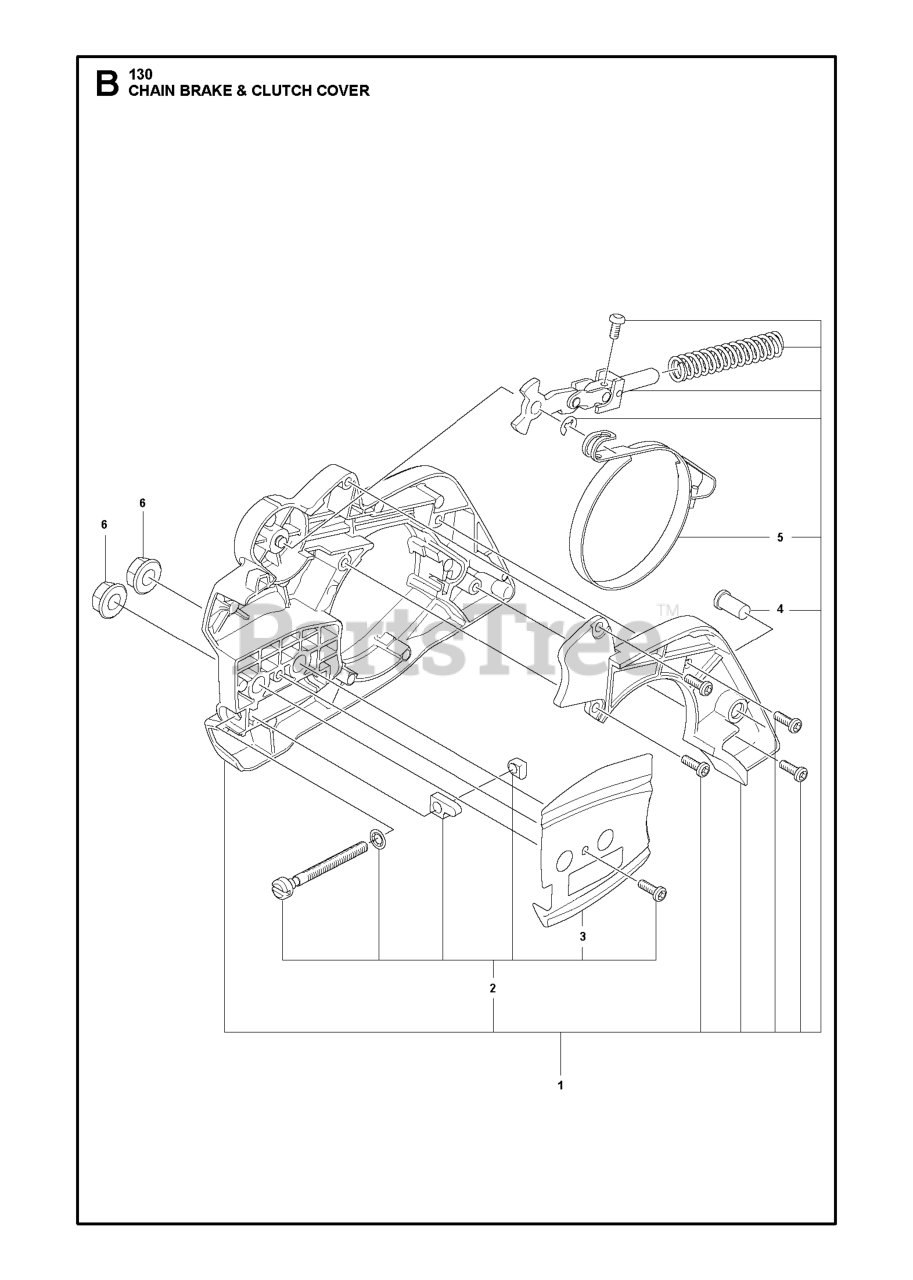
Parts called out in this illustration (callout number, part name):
1	SERVICE KIT CLUTCH COVER
2	SERVICE KIT BAR ADJUSTER
3	GUIDE PLATE CHAIN, OUTSIDE
4	GUIDE BUSHING
5	BRAKE BAND ASSY
